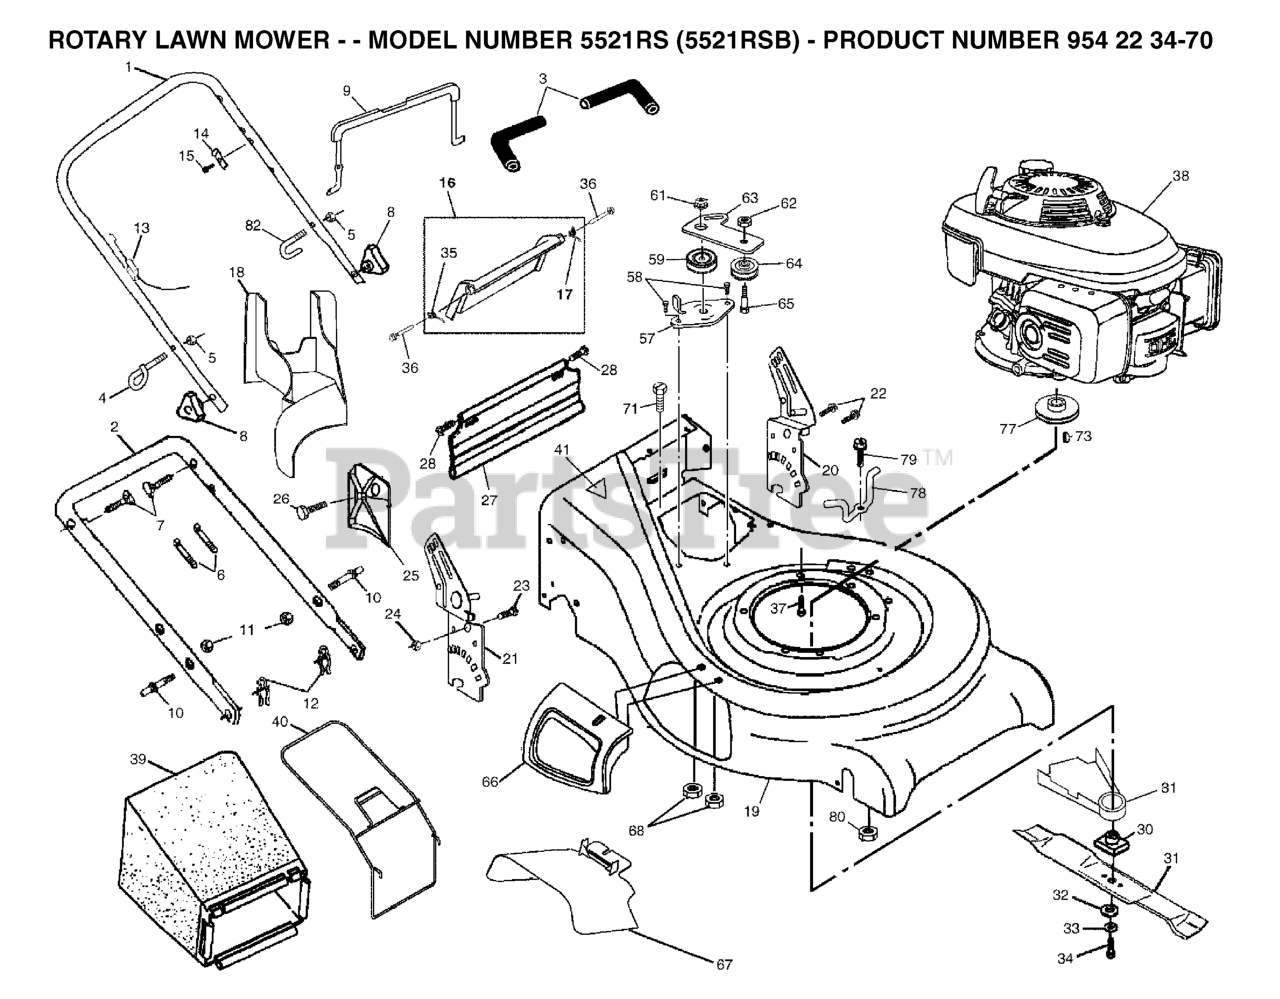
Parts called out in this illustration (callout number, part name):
2	HANDLE, LOWER
3	GRIP.HANDLE.FOAM.WIDE.(1 SIDE)
4	ROPE, GUIDE
5	NUT
6	TIE GUIDE
7	HANDLE BOLT
8	KNOB.HANDLE.STAR.HUSQ.GRAY
9	BAIL, FLAT AUTO WALK
11	NUT.CENTERLOCK.5/16-
12	HAIRPIN COTTER
13	ENGINE ZONE CONTROL CABLE
14	BRACKET UPSTOP
16	DOOR.REAR.PLASTIC.21.RWGD.BLAC
17	SPRING.RH.REAR.DOOR.21.RWGD
18	PLUG, MULCHER
22	SELF-TAPPING SCREW 5/16-18X3/4
23	BOLT, HEX HEAD 5/16-18
24	NUT.71038.31-18.HEX.NYLOCK
25	CLIPPING DEFLECTOR
28	HINGE SCREW
30	BLADE ADAPTER
31	BLADE
32	WASHER,HARDEN
33	LOCKWASHER
34	SCREW, HEX HD 3/8-24 X 1-3/8
35	SPRING.LH.REAR.DOOR.21.RWGD
37	BOLT 3/8-16X1-1/8
40	GRASS CATCHER FRAME
41	DECAL HYT
57	BRACKET ASSEMBLY
59	PULLEY ASSY
61	NUT
62	LOCKNUT
63	IDLER ARM
64	IDLER PULLEY
65	SHOULDER BOLT
66	MULCHER DOOR ASM.
67	DEFLECTOR, DISCHARGE
73	HI-PRO KEY
77	PULLEY.ENG.25MMM
78	KEEPER.BELT.21.RWGD.EZ
79	SCREW.#8.MACH
80	NUT.HEX.#8
81	SHIELD.DEBRIS.ASM.21.RWGD
